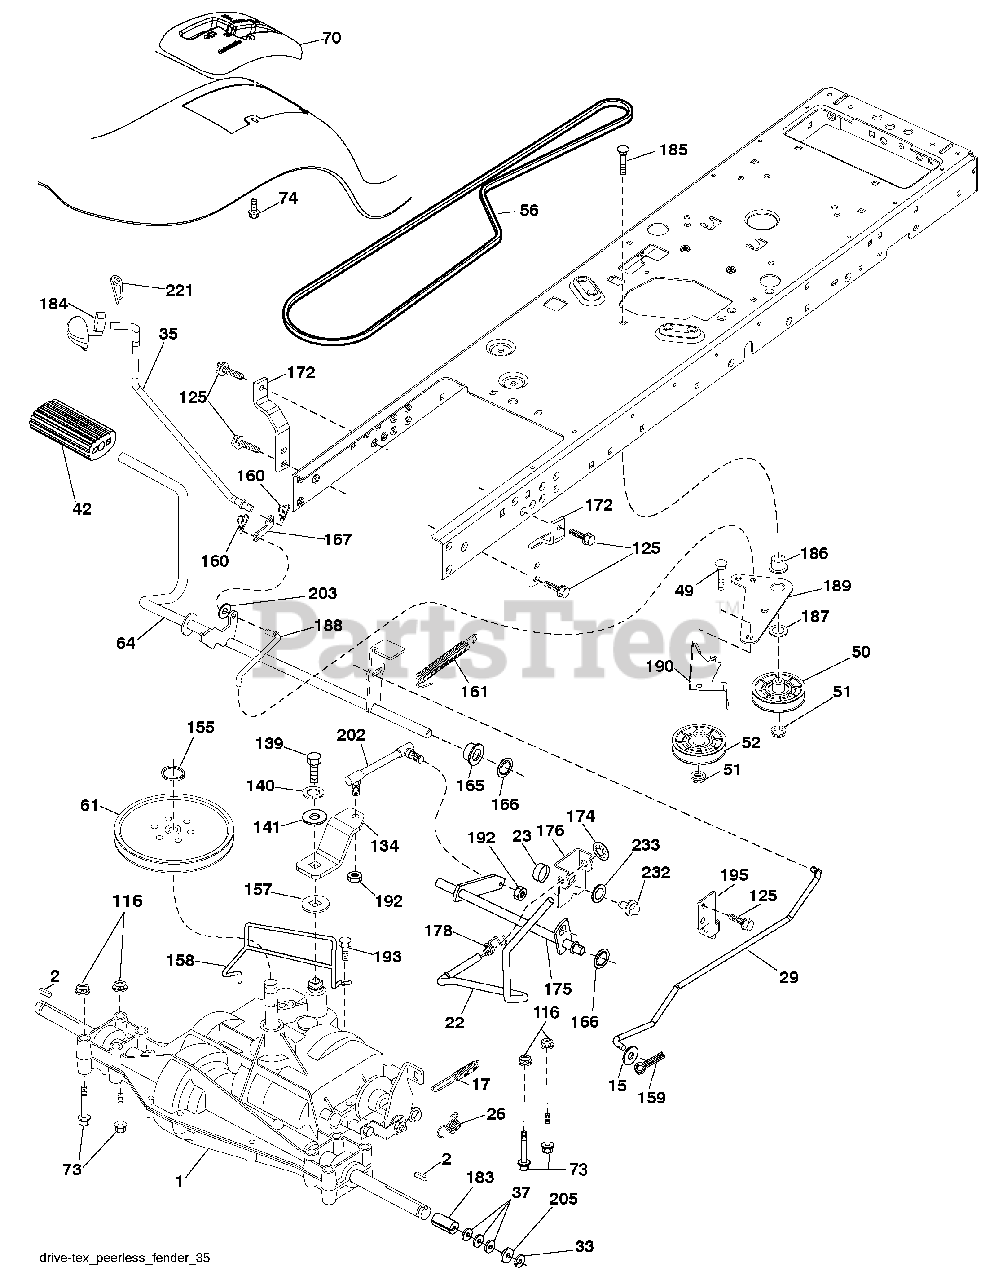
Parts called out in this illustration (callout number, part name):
2	Key Square
15	Washer 13/32 x 13/16 x 16 Ga.
17	Spring, Brake
22	Rod Shift
23	Knob
26	Spring Brake RTN
29	Rod, Brake
33	Ring E
35	Rod, Brake, Park
37	Washer 25/32 x 1-1/4 x 16 Ga.
42	Cover, Foot Pedal
49	Bolt
50	Pulley Idler Flat
51	Lock Nut 3/8-16
52	Idler V-Groove
56	V-Belt, Drive
61	Pulley Transaxle
64	Shaft Asm. Pedal Brake Control
70	Console
73	Bolt 5/16-18 Gr. 5
74	Screw 1/4 x 1/2
116	Nut Lock Hex Flange 5/16-18
125	Screw 5/16-18 x 3/4
134	Arm Shift
139	Bolt 1/4-20 unf Gr. 8 w/Patch
140	Washer Lock Hvy Helical 1/4
141	Washer 9/32 x 3/4 x 10 Ga.
155	Ring Retainer
157	Washer Plate Shf
158	Keeper T/A
159	Pin Cotter 1/8 x 3/4
160	Retainer Clip
161	Spring, Return, Clutch
165	Busing Shaft Brake Hand Control
166	Nut Push .625
167	Latch Brake Parking
172	Strap Torque LH
174	Nut Push
175	Shaft Asm Shift
176	Arm Clevis Rod Shift
178	Spring Shift
183	Spacer, Axle
184	Handle Parking Brake
185	Bolt
186	Spacer Retainer
187	Washer
188	Link Clutch Ground Drive
189	Bellcrank Ground Drive
190	Keeper Bellcrank Ground Drive
192	Nut Lock Center 1/4-28
193	Screw 5/16-18 x 3/4
195	Bracket Brake Rod
202	Link Shift
203	Washer 11/32 x 11/16 x 16 Ga.
205	Washer 25/32 x 1-5/8 x 16 Ga.
221	Retainer Spring Clip Handle
232	Bolt 7/16-14 x 1 Gr. 5
233	Washer Serrated
